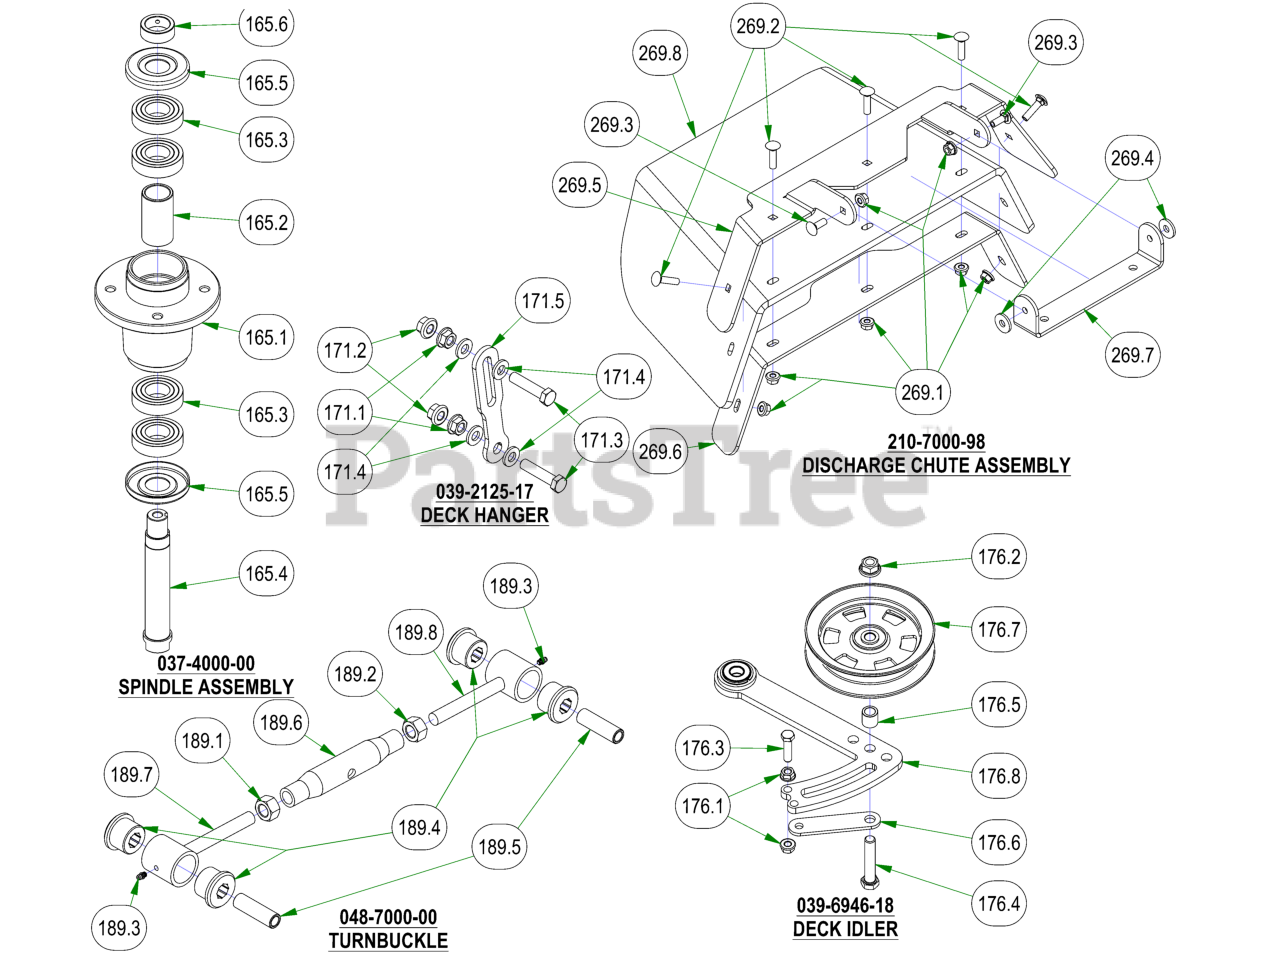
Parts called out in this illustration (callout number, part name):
165	OUTLAW SPINDLE ASSEMBLY
165.1	4000 Series Spindle Housing
165.2	4000 Series Spindle Spacer
165.3	Bearing - 6206
165.4	Spindle Shaft
165.5	Spindle Dust Cap
165.6	Locking Collar w/ 1/4"-20 Set Screw
171	Deck Hangar Assembly
171.1	1/2-13 HEX SERRATED FLANGE NUT HARD/ZINC
171.2	1/2-13 NYLON INSERT FLANGE LOCKNUT ZINC
171.3	1/2-13 X 2-1/4 HEX CAP SCREW (GR.5) ZINC
171.4	.505 ID X 1.000 OD X .125 THICK FLAT WASHER NYLON
171.5	Deck Hangar
176	2019 Rebel Rogue Deck Idler
176.1	3/8-16 HEX SERRATED FLANGE NUT HARD/ZINC
176.2	1/2-13 NYLON INSERT FLANGE LOCKNUT ZINC
176.3	3/8-16 X 1-1/2 HEX CAP SCREW (GR.5) ZINC
176.4	1/2-13 X 2-3/4 HEX CAP SCREW (GR.5) ZINC
176.5	.51 ID X .75 OD X .75 LGTH SOLID SPACER ZINC
176.6	Belt Tensioner Retainer Plate
176.7	5" Idler Pully
176.8	2019 Deck Tensioner
189	Turnbuckle
189.1	11/16-12 Hex Nut-2015 Toplink
189.2	11/16-12 Lefthand Hex Nut-Topl
189.3	1/4" Press in Grease Fitting
189.4	Polyeurethane Bushing
189.6	2015 Outlaw Toplink Body
189.7	2015 Outlaw Toplink RH End
189.8	2015 Outlaw Toplink LH End
269	2019 Outlaw Gen2 Chute Assembly
269.1	5/16-18 NYLON INSERT FLANGE LOCKNUT ZINC
269.2	5/16-18 X 1-1/4 CARRIAGE BOLT ZINC
269.3	5/16-18 X 7/8 CARRIAGE BOLT ZINC
269.4	.360 ID X .983 OD X .120 THICK FLAT WASHER NYLON
269.5	2019 Upper Chute Bracket
269.6	2019 Lower Chute Bracket
269.7	2019 Chute Hanger
269.8	2019 Belted Chute with Logo
